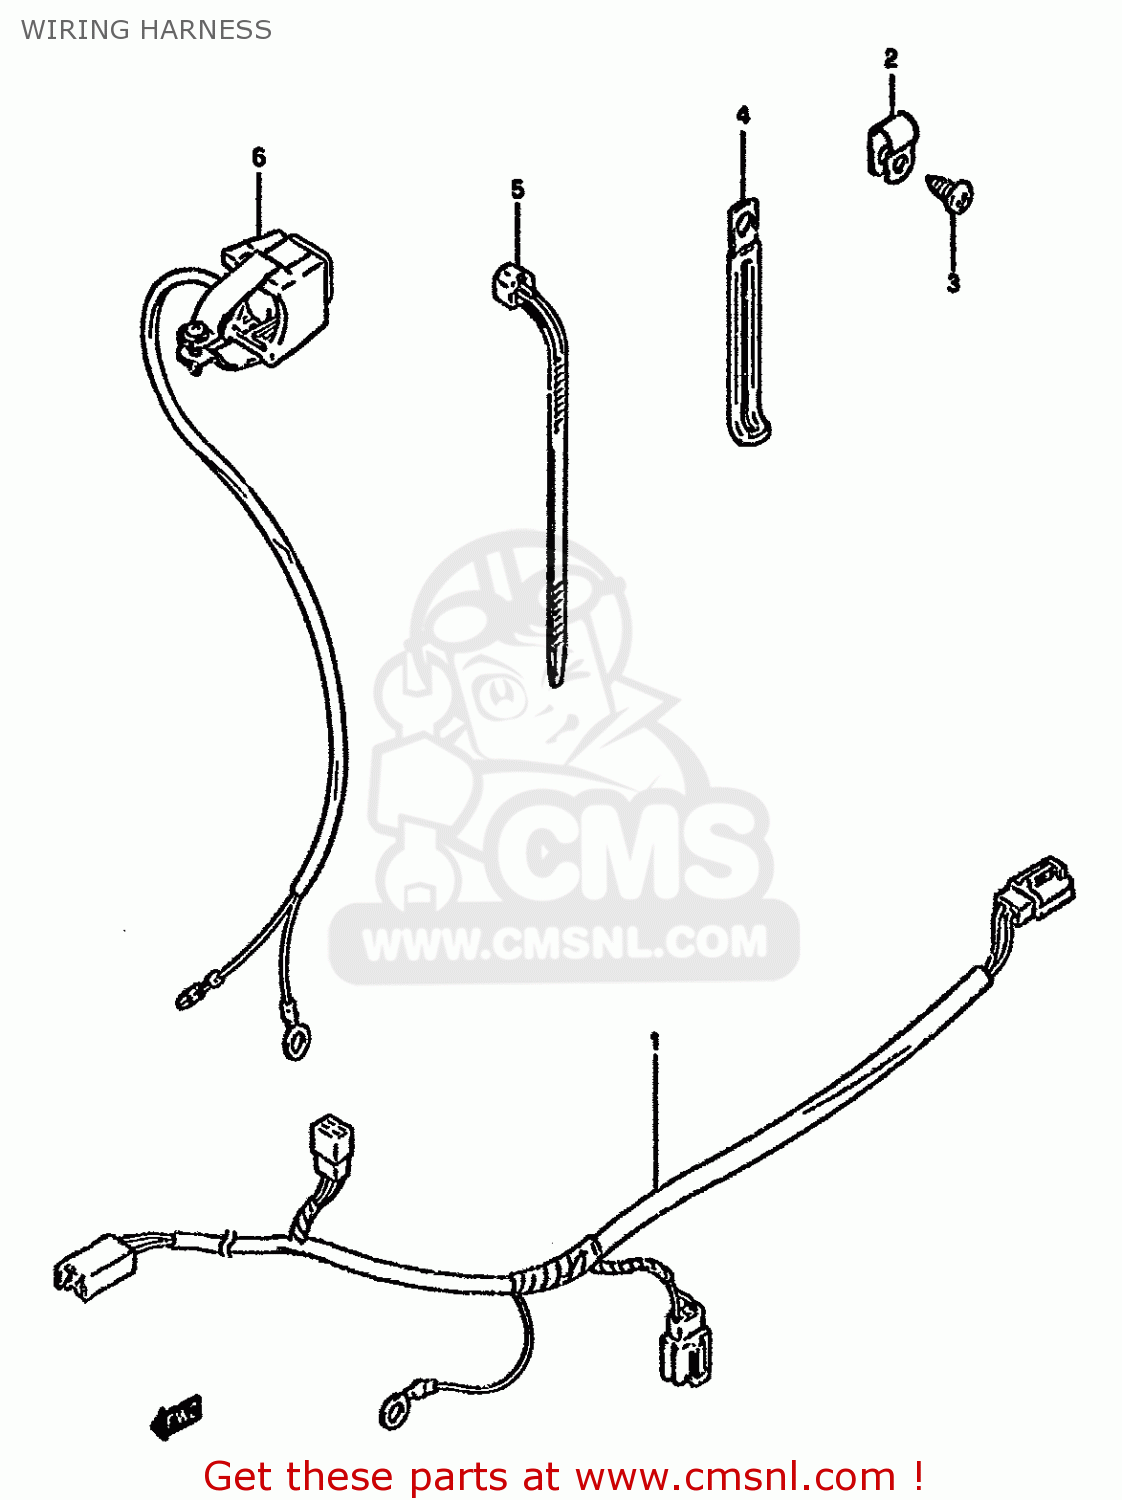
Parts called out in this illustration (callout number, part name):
1	HARNESS,WIRING
2	CLAMP
3	SCREW
4	CLAMP
5	CLAMP L:165
6	SWITCH ASSEMBLY
